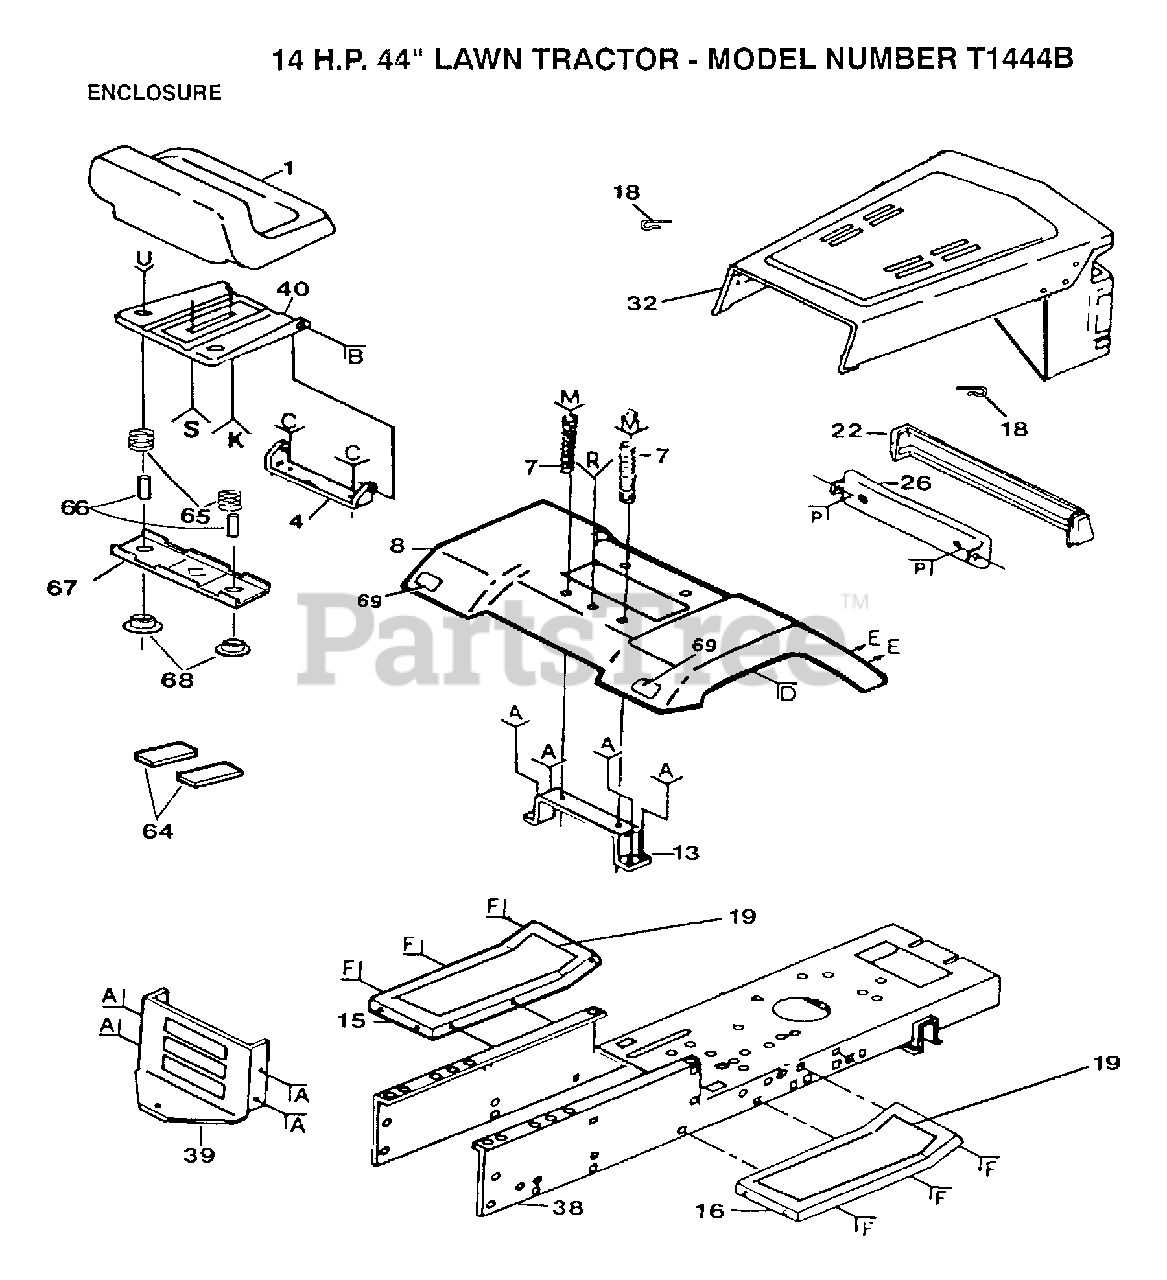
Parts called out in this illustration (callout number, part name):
7	SPRING COMPRESSIO
18	SPRING.RETAINER
19	"PAD,FOOTREST"
32	HOOD&GRILL ASSY
38	DRAWBAR LT/YT
39	CHASSIS ASSY
64	STRIP FORM
65	SPRING COMPRESSED
66	SPACER SPLIT
67	BRKT SWITCH
68	BUSHING
69	REFLECTOR-TAIL YT
